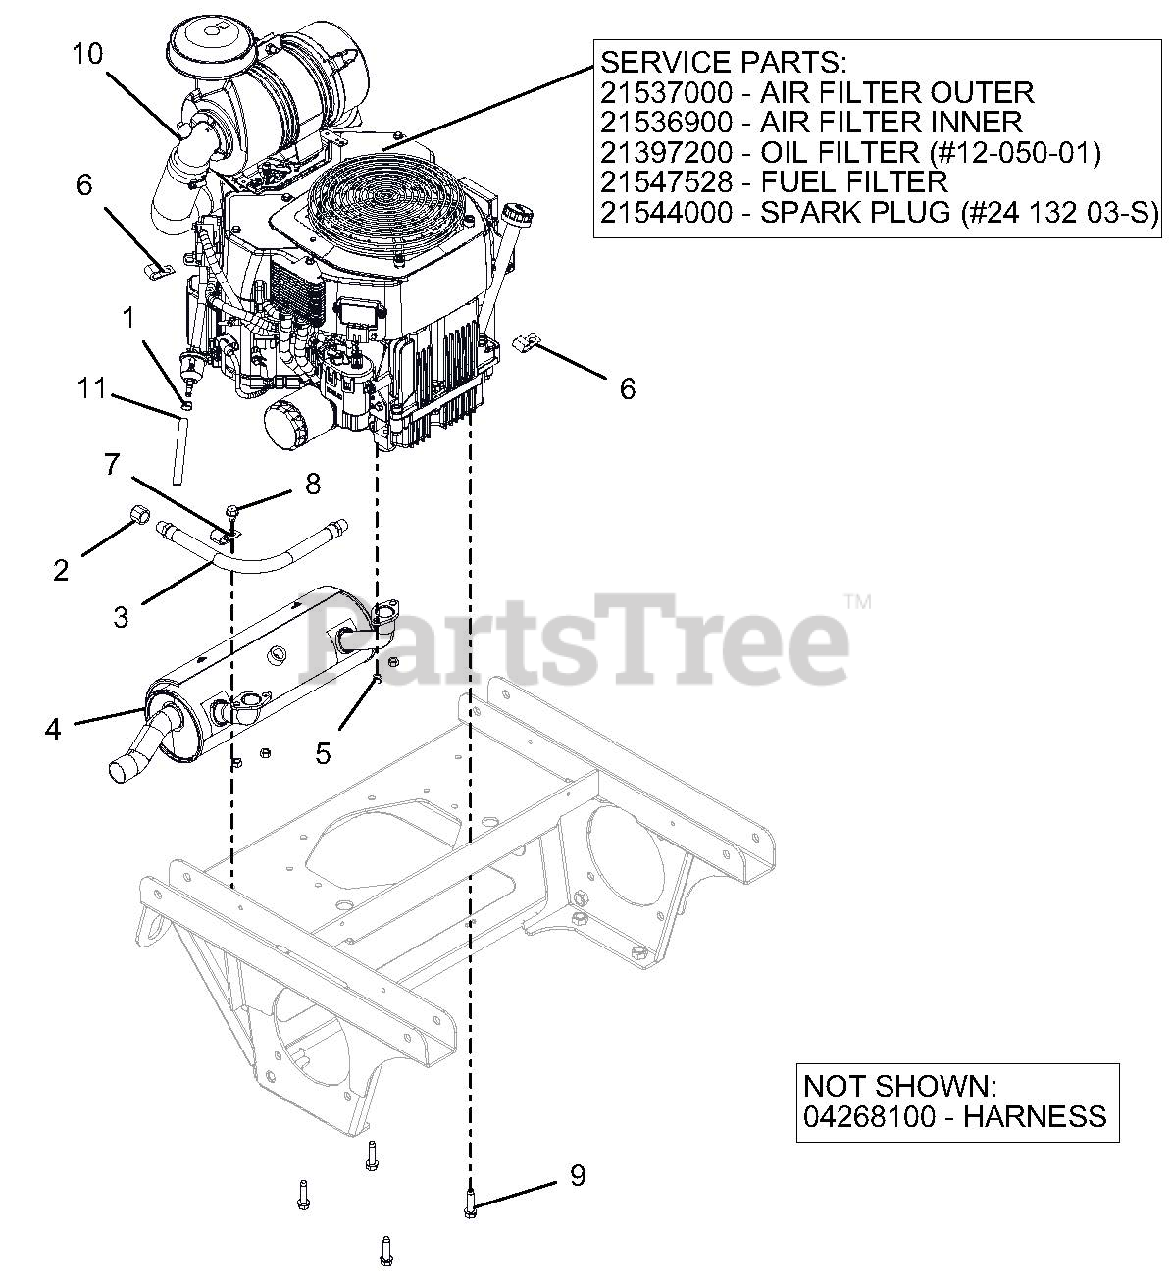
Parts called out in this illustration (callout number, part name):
1	CLAMP, FUEL LINE
2	PIPE, CAP 3/8 NPT FEMALE
3	HOSE, HYD .38-11-OK M6N0-M6N0
4	MUFFLER, KOHLER EFI
5	NUT-LK-TOP M8-1.25 YWZC
6	CLAMP, J
8	SCR-TAP .38-16X.50 HWH TR YWZ
9	SCR-TAP .38-16X1.50 HWH TR YZ
10	ENGINE, KOHLER EFI ECV749
10	AIR FILTER OUTER
10	AIR FILTER INNER
10	OIL FILTER
10	FUEL FILTER
10	SPARK PLUG
11	.25 LOW-PERM GAS HOSE 47.00" LG - VALVE TO ENGINE
